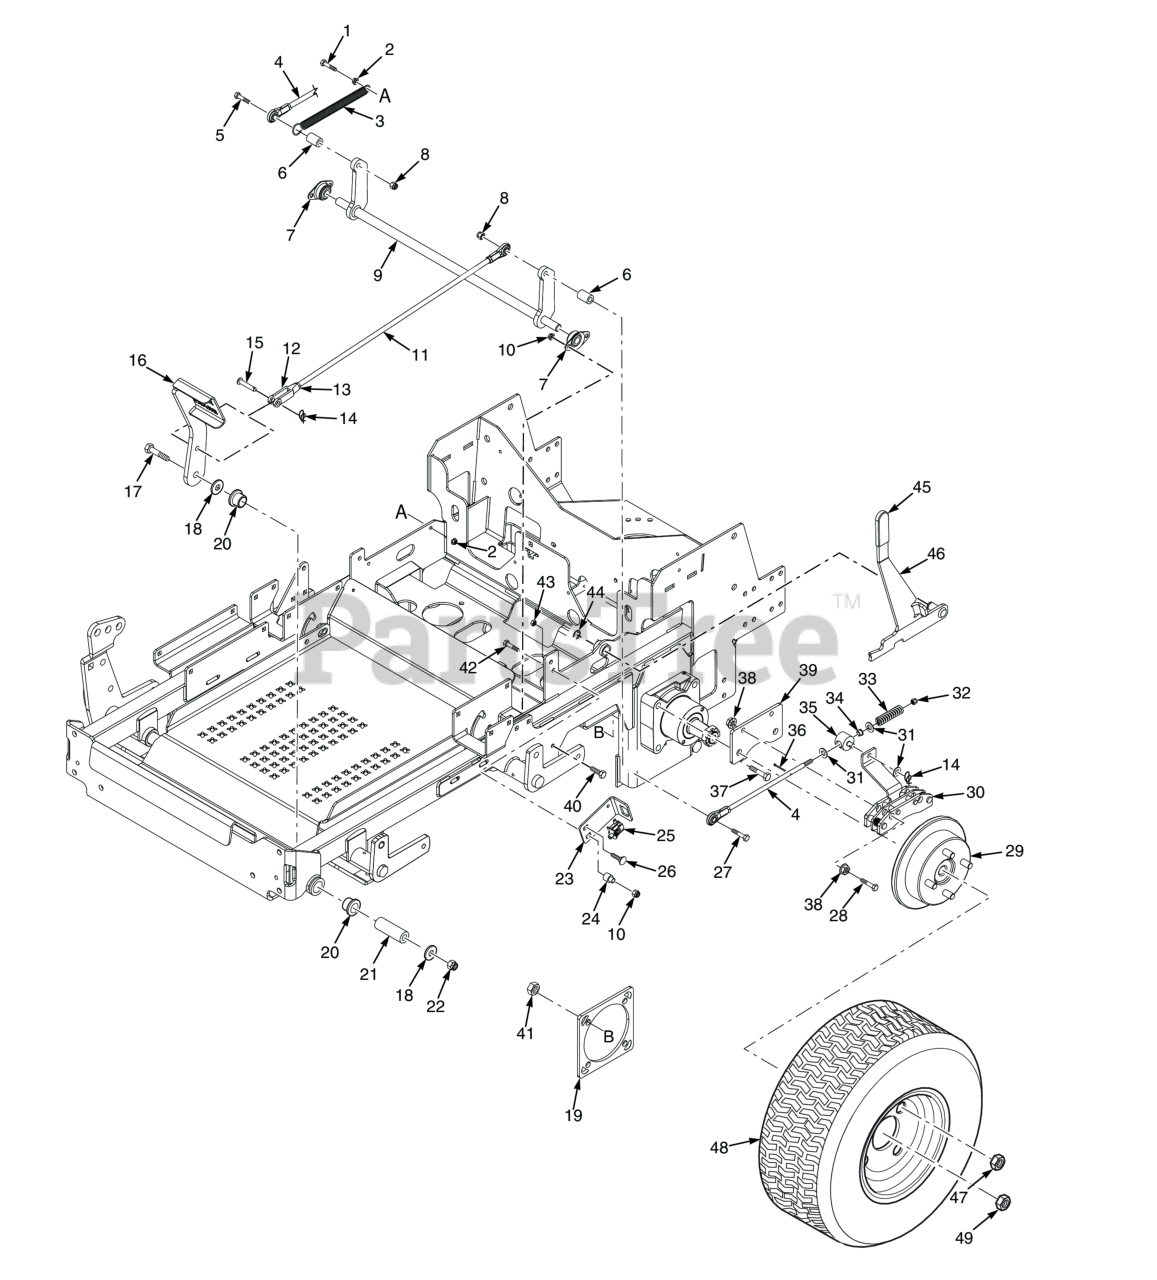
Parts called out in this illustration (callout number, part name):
1	SERR. FLG. HEX HEAD CAPSCREW, 5/16-18 X 3/4
2	NUT, 1/4-20 SERRATED FLANGE HEX HEAD
3	Spring, Brake Return
4	Brake Link Assembly
5	Bolt, Hex Head 3/8-16 x 3" - 52"
6	Spacer
7	Bearing, Self Aligning - 5/8 I.D.
8	Nut, Flange Elastic Stop Nut, 3/8-16
9	Brake Bellcrank Weldment
10	HEX NUT, ELASTIC STOP LOCK, 5/16-18
11	Brake Rod Assembly
12	Clevis, Traction Control
13	Nut, 3/8-24 UNF R.H. Thread
14	Pin, Rue Cotter 3/8" Diameter
15	Pin, Clevis 3/8-16 x 1-1/16"
16	Brake Pedal Weldment
17	Bolt, Hex Head 1/2-13 x 4-1/4"
18	Flat Washer, 1/2 (.562 x 1.375 x .109)
19	Plate Weldment, Motor Backing
20	Bearing, Plastic
21	Sleeve, Brake Pivot
22	HEX LOCKNUT, ELASTIC STOP, 1/2-13
23	Switch Mounting Bracket, Brake
24	Spacer, Pump Dampener
25	Switch, Interlock, Normally Open
26	Serr. Fl. Hex Head CPSCR, 1/4-20 x 3/4"
27	Bolt, Hex Head 3/8-16 x 3" - 52"
28	Bolt, Hex Head 1/2-13 x 4" (lower)
29	Wheel Hub w/Disc
30	Brake Caliper
31	Flatwasher, 3/8 (.406 x .812 x .065)
32	Nut, Elastic Stop 3/8-16, grade 8 black
33	Spring, Brake
34	Bearing
35	Swivel Assembly, Brake
36	Pin, Cotter 3/32 x .75"
37	Bolt, Hex Head 1/2-13 x 2-3/4" (48V & 52V - One Weight)
38	Nut, Hex Serrated Flange 1/2-13
39	Mounting Bracket, Brake
40	BOLT, SERRATED FLANGE HEX HEAD 5/16-18 X 3/4"
41	Locknut, Hex 1/2-13 Center Lock
42	Bolt, Hex Head 5/16-18 x 1-1/2" - Front
43	HEX, NUT, ELASTIC STOP LOCK, 1/4-20
44	RETAINING RING, 5/8" EXTERNAL "E"
45	Grip, Brake Handle
46	Lever w/Grip, Parking Brake
47	Wheel Nut, 1/2-20 x 13/16
48	Wheel Assy 24 x 9.5-12 (52" Deck)
49	Nut, Hex Castle 1.0-20 UNEF
